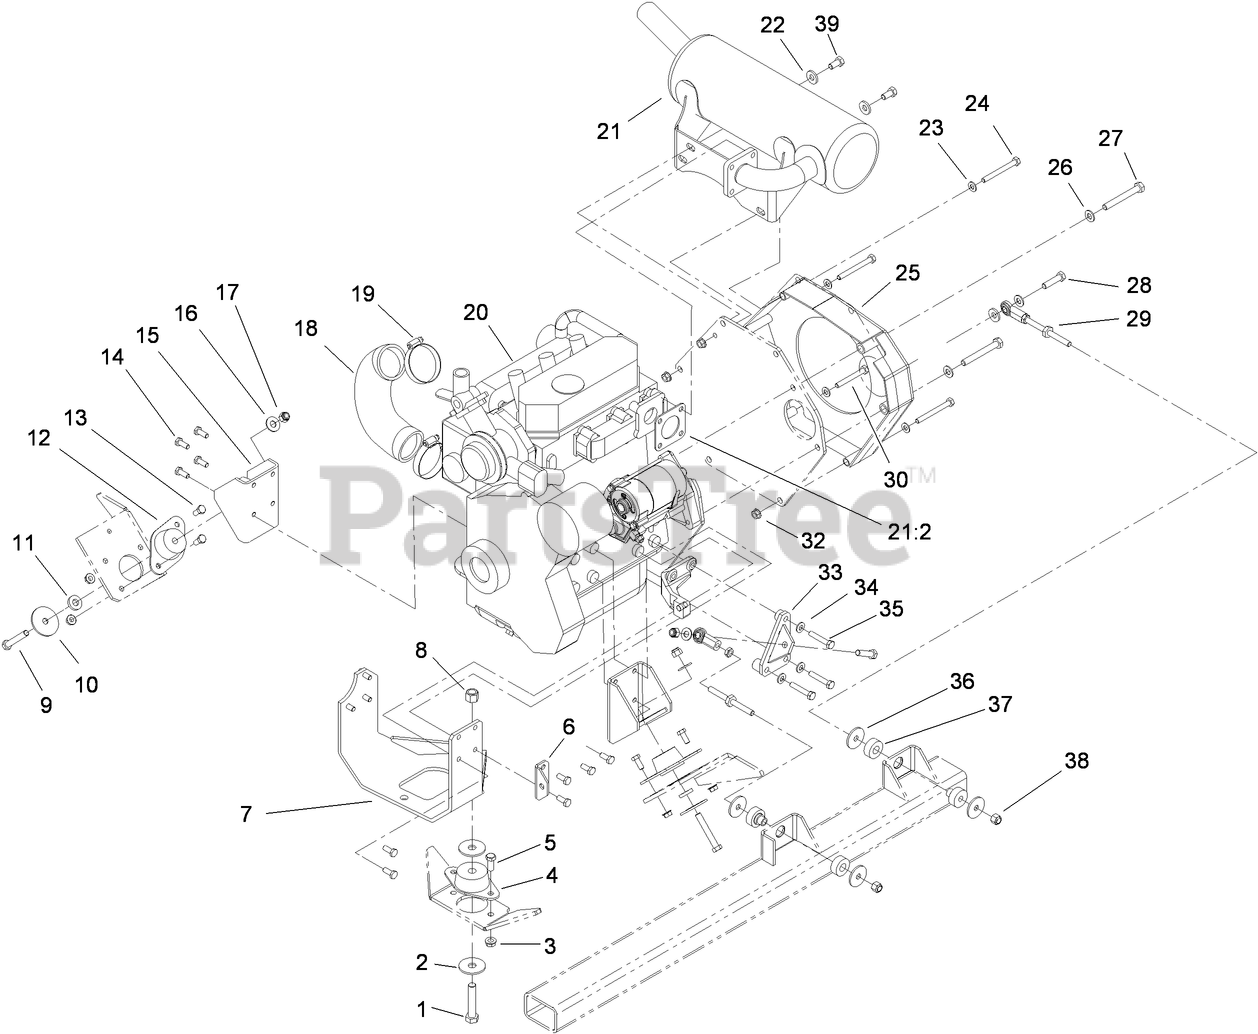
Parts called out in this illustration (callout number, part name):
1	SCREW-HH
2	WASHER-THRUST
3	NUT-HHF, WHIZ
4	ISOLATOR-REAR
5	SCREW-HH
6	BRACKET-GROUND
7	REAR ENGINE MOUNT ASM
8	NUT-LOCK, NI
9	SCREW-HH
10	WASHER-FLAT
11	WASHER
12	ISOLATOR-SIDE
13	SCREW-HH
14	SCREW-HH
15	LH AND RH ENGINE MOUNT ASM
16	WASHER-FLAT
17	NUT-LOCK, NI
19	CLAMP-HOSE
20	ENGINE-DAIHATSU
21	MUFFLER KIT
21:2	GASKET-MUFFLER
22	WASHER-BELLEVILLE
23	WASHER-PLAIN
24	SCREW-HH
25	COVER-FLYWHEEL
26	WASHER-FLAT
27	SCREW-HH
28	SCREW-HH
29	BALL JOINT LINK ASM
30	SCREW-HH
32	NUT-HF
33	BRACKET-ENGINE, FRONT
34	WASHER-SPRING
35	Screw-HH
36	WASHER
37	ISOLATOR-LINK
38	NUT-LOCK
39	SCREW-CAP
